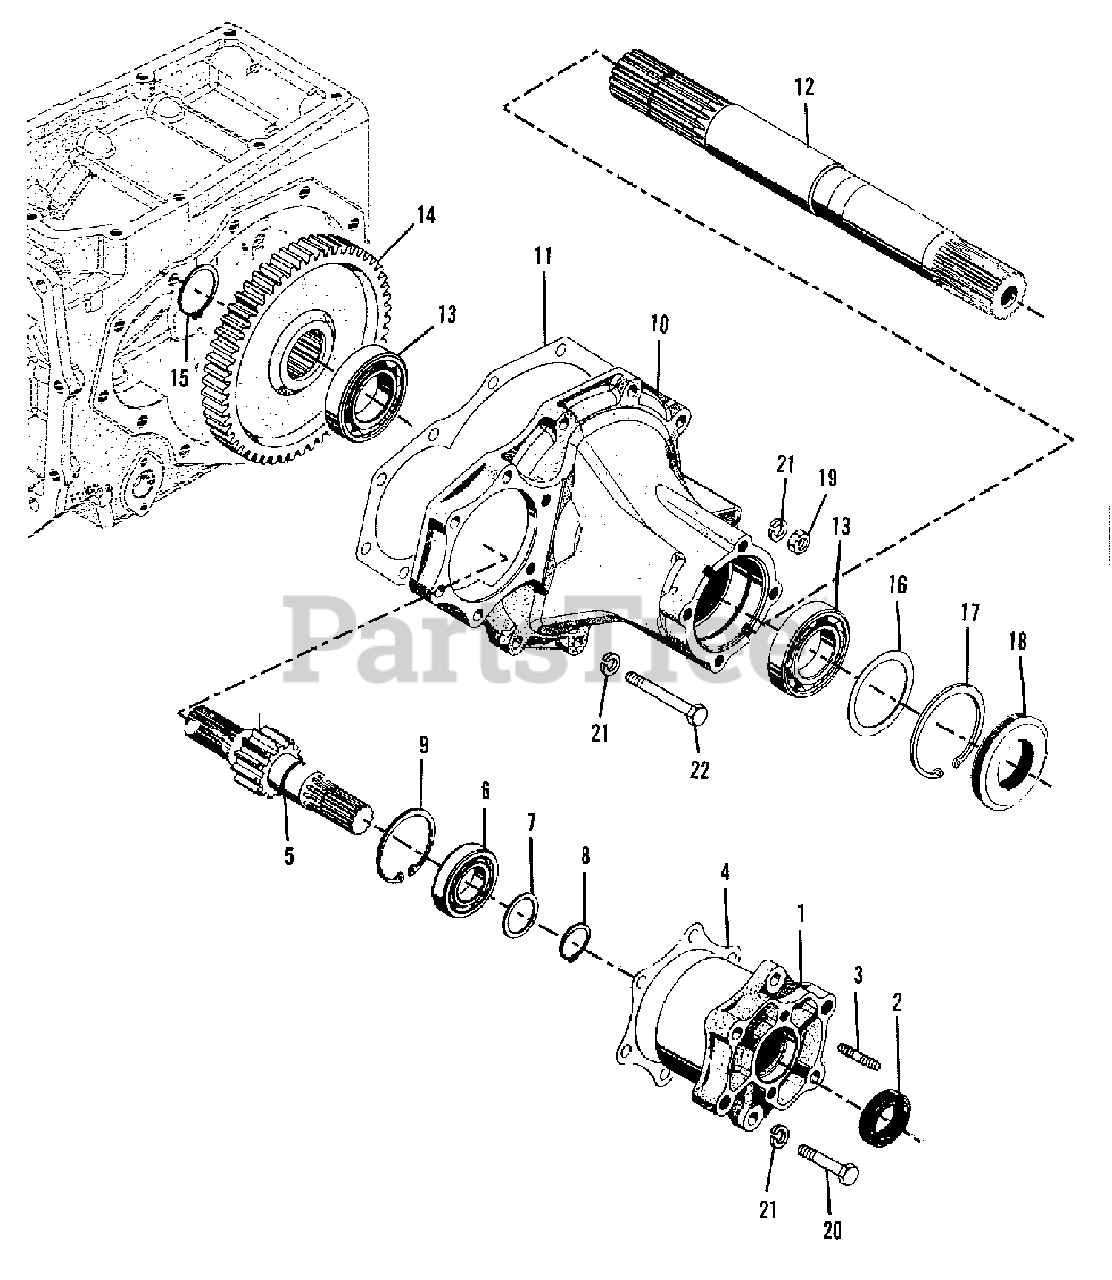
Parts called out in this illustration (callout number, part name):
1	HOUSING ASSEMBLY, L.H. axle pinion (Incl. Items 2 & 3)
2	SEAL, oil
3	STUD, M10 x 18
4	SHIM (0.1)
4	SHIM (0.15)
4	SHIM (0.2) (Select One)
4	SHIM (0.3)
4	SHIM (0.5)
5	SHAFT, L.H., axle pinion
6	BEARING, ball (One side sealed)
7	WASHER, thrust
8	RING, M35, snap-external
9	RING, M72, snap-internal
12	AXLE, final drive
13	BEARING, ball
14	GEAR, final drive
15	RING, M50, snap-external
16	WASHER (0.4)
16	WASHER (0.6) (Select One)
17	RING, M90, snap-internal
18	SEAL ASSEMBLY, oil
20	SCREW, M12 x 65
21	LOCKWASHER, M12
22	CAPSCREW, M12 x 45
